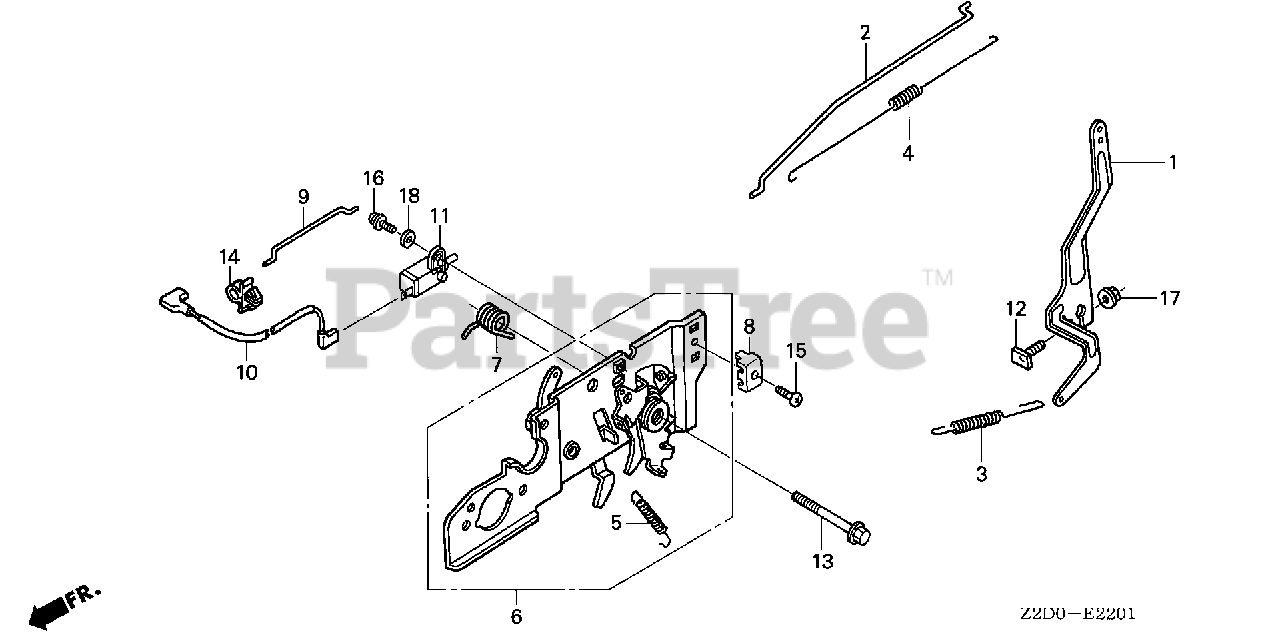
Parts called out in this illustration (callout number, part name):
1	ARM, GOVERNOR
2	ROD, GOVERNOR
3	SPRING, GOVERNOR
4	SPRING, THROTTLE RETURN
5	SPRING, LEVER
6	BASE, CONTROL
8	HOLDER, CABLE
9	ROD, CHOKE
12	BOLT, GOVERNOR ARM
13	BOLT, FLANGE (6X45) (CT200)
15	SCREW, PAN (5X16)
17	NUT, FLANGE (6MM)
